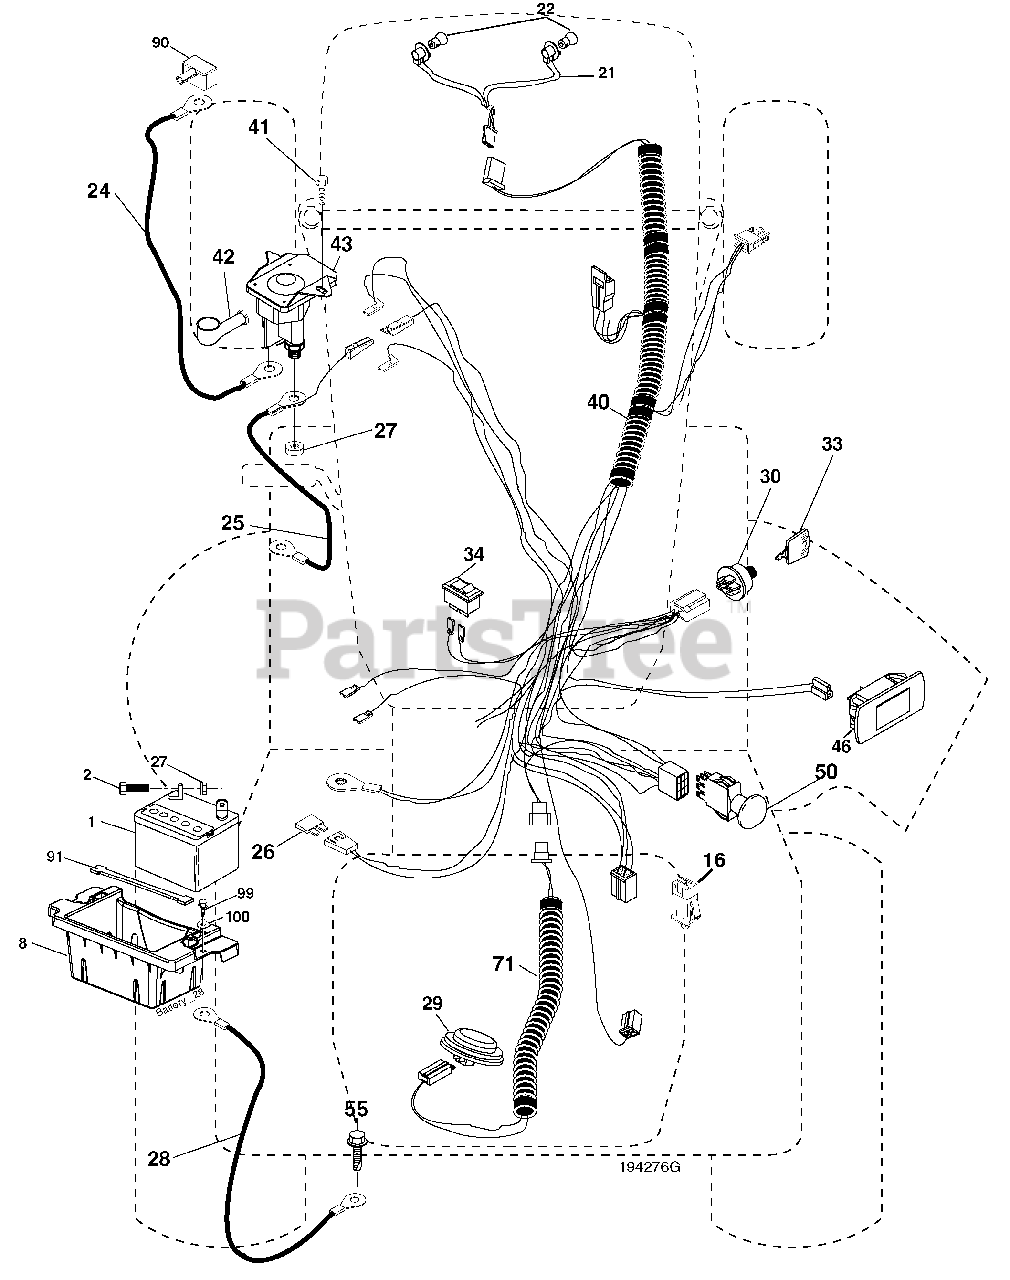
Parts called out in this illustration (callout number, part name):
1	Battery
2	Bolt Hex Head 1/4-20 x 3/4
8	Box Battery
16	Switch Interlock Push-In
21	Harness Socket Light W/4152J
22	Bulb Light
24	Cable Battery
25	Cable Starter
26	Fuse
27	Nut Keps Hex 1/4-20 unc
28	Cable, Ground
29	Switch, Seat
30	Switch, Ign
33	Key, Ignition
34	Switch Light / Reset
40	Harness Ign.
41	Screw Thd Cut 1/4-20 x 1/2
42	Cover, Terminal
43	Solenoid
46	Gauge Hourmeter
50	Switch PTO
55	Screw Thdrol 5/16-18 x 3/4 TYTT
71	Harness Ign. Dash
90	Cover Terminal Battery
91	Strap Battery Mount Front
99	Screw Hexwsh Thdrol 1/4-20 x 3/4
100	Washer 9/32 x 7/8 x 16 Ga.
